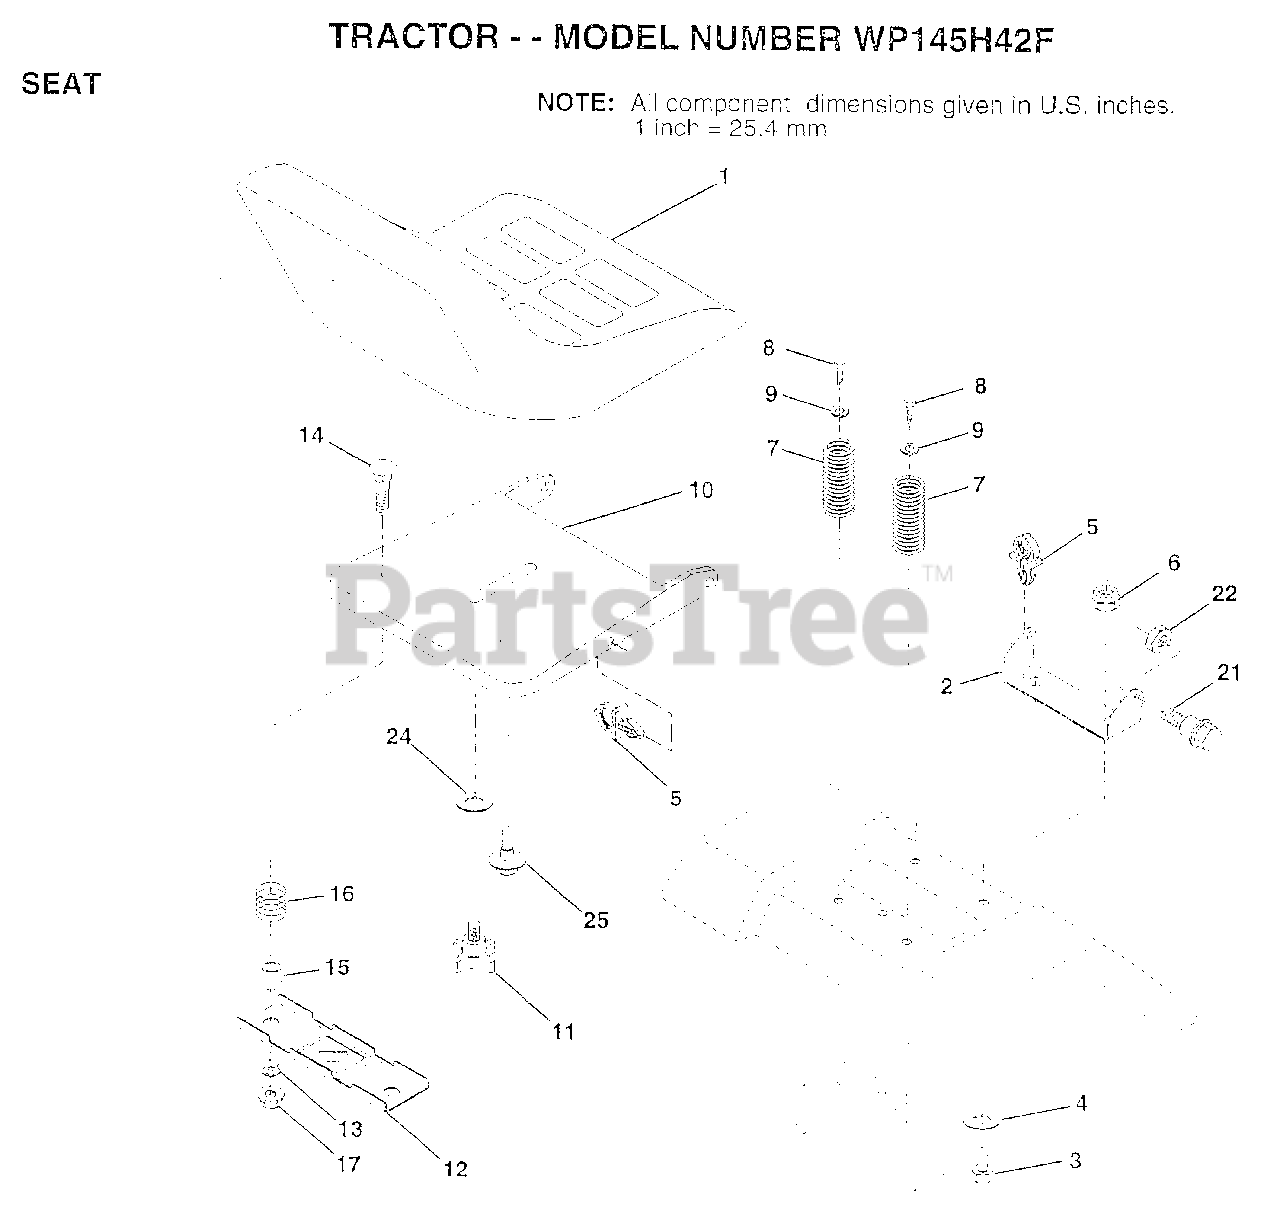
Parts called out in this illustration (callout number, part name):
2	BRACKET PVT SEAT
3	BOLT
4	WASHER PM
5	CLIP.PUSH-IN.HING
6	NUT
7	SPRING COMPRESSIO
8	SCREW GTV
9	WASHER
10	PAN-SEAT
11	"KNOB 1/2"" YT"
12	BRKT SWITCH
13	BUSHING
14	BOLT-RD HD SQ NK
15	SPACER SPLIT
16	SPRING COMPRESSED
21	"BOLT,SHOULDER"
24	WASHER
25	"BOLT,SHOULDER"
